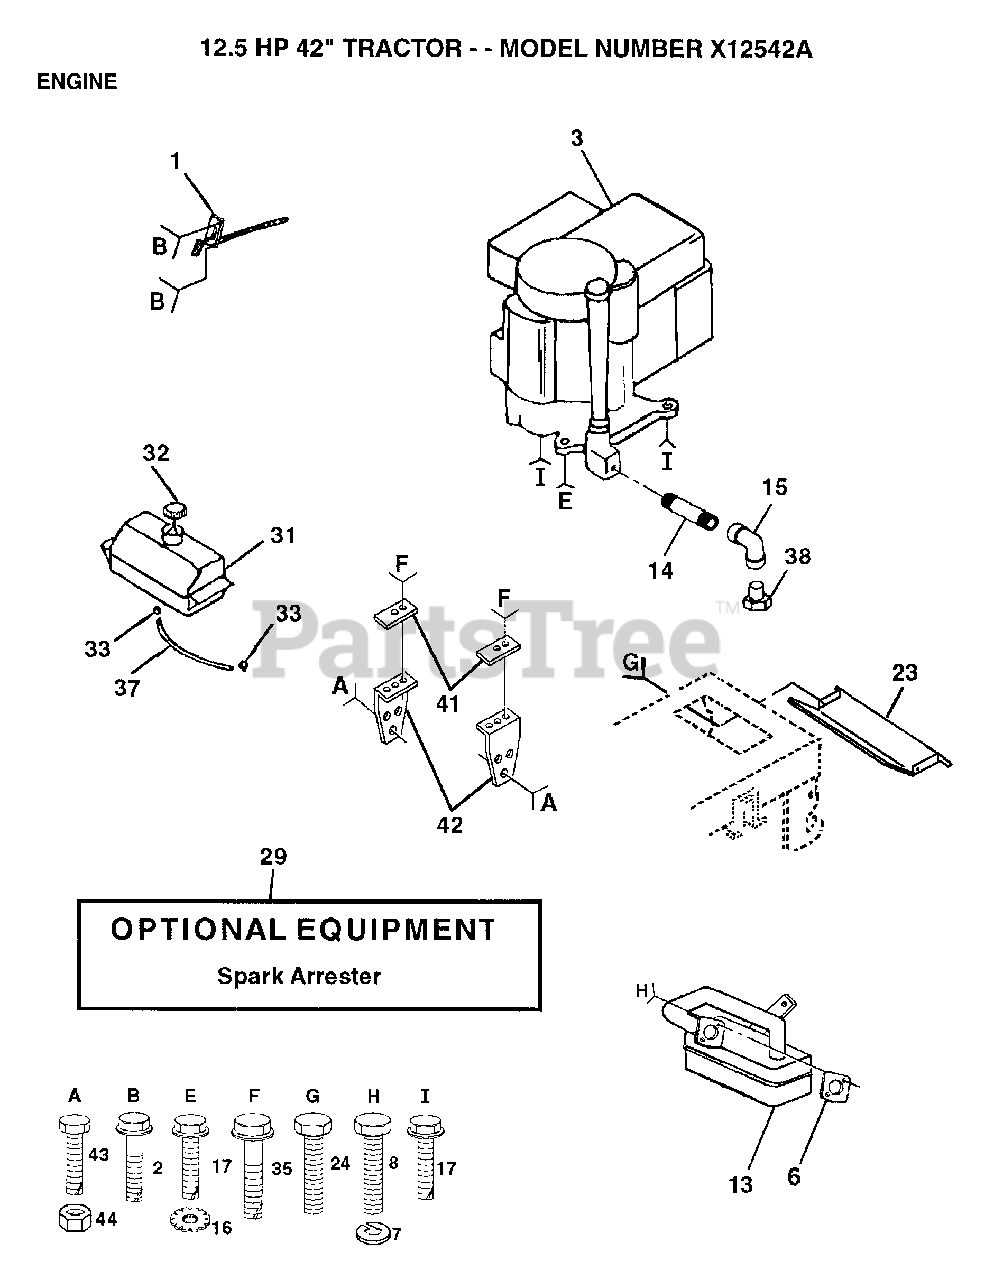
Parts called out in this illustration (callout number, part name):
1	"CONTROL,THROTTLE"
2	SCREW LT
7	LOCKWASHER
8	SCREW
13	MUFFLER
14	PIPE NIPPLE
15	ELBOW
16	LOCKWASHER
17	SCREW
23	HEAT SHIELD
24	SCREW
31	TANK.FUEL.LT.
33	HOSE CLAMP
35	SCREW
37	HOSE T
41	"CLAMP,FUEL TANK T"
42	BRKT FUEL TANK T
43	BOLT
